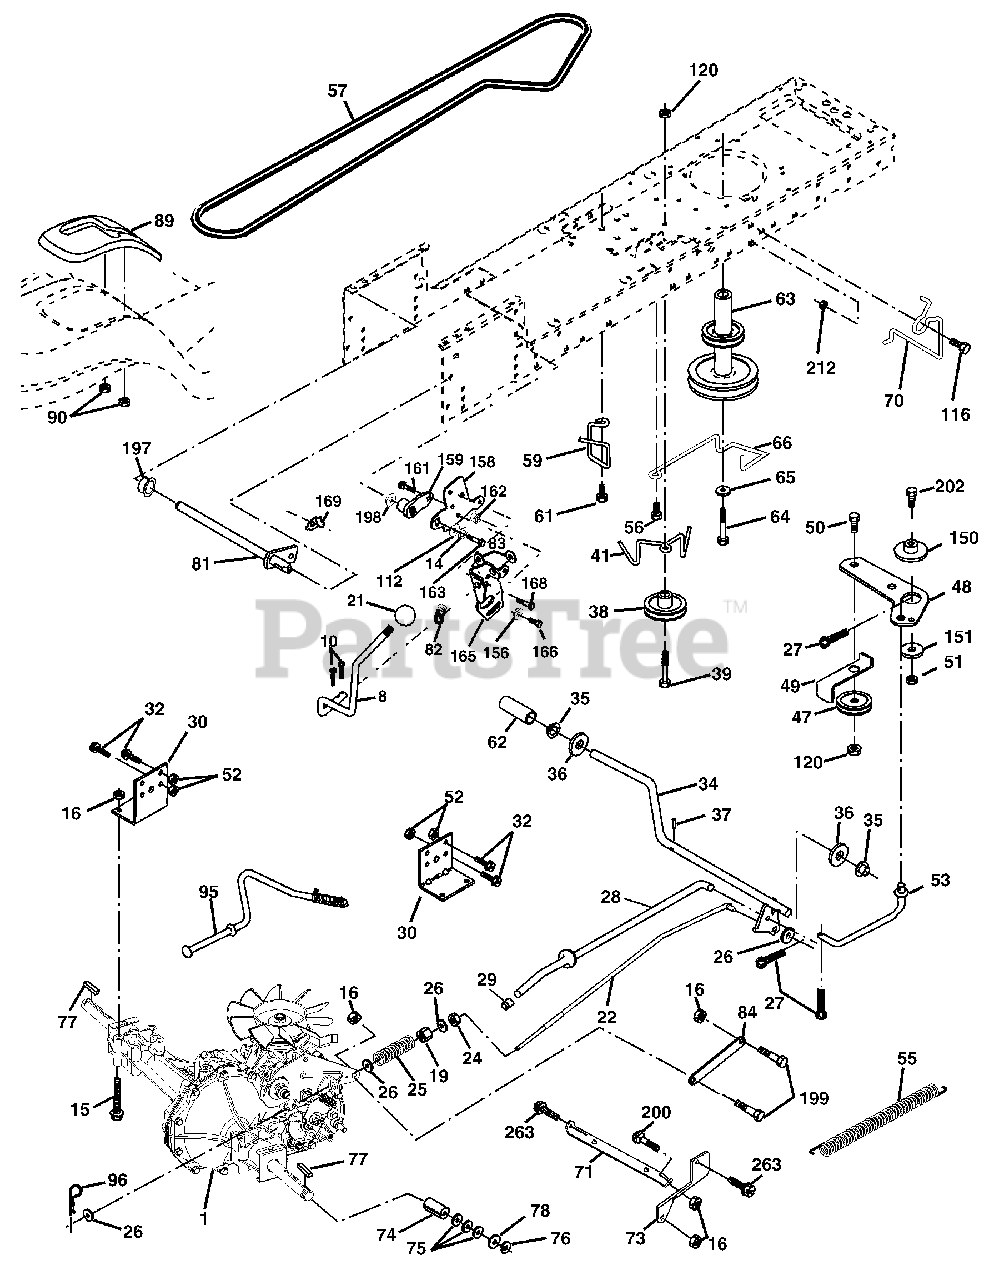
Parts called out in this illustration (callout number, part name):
8	Rod Shift
10	Pin Cotter 1/8 x 1 CAD
14	Washer Lock Hvy Helical
15	Bolt, Hex FLGHD 5/16-18 Gr. 5
16	Nut Lock Hex W/Ins 5/16-18
19	Nut Lock Hex W/Wsh 3/8-16
21	Knob, Round 1/2-13
22	Rod, Brake Hydro
24	Nut
25	Spring, Brake Rod
26	Washer
27	Pin Cotter 1/8 x 3/4 CAD.
28	Rod, Parking Brake
29	Cap, Parking Brake
30	Bracket, Transaxle
32	Bolt Hex Hd 5/16-18 unc x 3/4
34	Shaft, Foot Pedal
35	Bearing, Nylon
36	Washer
37	Pin, Roll
38	Pulley, Composite
39	Bolt Rdhd 3/8-16 unc x 2-3/4 Gr
41	Keeper, Belt Idler
47	Pulley, Idler, V-Groove
48	Bellcrank Clutch Grnd Drv STL
49	Retainer, Belt
50	Bolt Carr Sh 3/8-16 x 1-1/2 Gr. 5
51	Nut Crownlock 3/8-16 unc
52	Nut Crownlock 5/16-18 unc
53	Link, Clutch
55	Spring, Return, Clutch
56	Screw 3/8-16 x 1-1/4
57	V-Belt, Ground Drive
59	Keeper, Center Span
61	Screw 3/8-16 x .875
62	Cover, Pedal
63	Pulley, Engine
64	Bolt Hex 7/16-20 x 4 x Gr. 5-1.5
65	Washer
66	Keeper Belt Engine
70	Guide Belt
71	Strap Torque Lh Hydro
73	Strap Torque Rh Hydro
74	Spacer, Axle
75	Washer 25/32 x 1-1/4 x 16 Ga.
76	E-Ring
77	Key, Square
78	Washer 25/32 x 1-5/8 x 16 Ga.
81	Shaft Asm. Cross Hydro
82	Spring Torsion T/A
83	Washer 17/32 x 3/4 x 16 Ga.
84	Link Transaxle
89	Console, Shift
90	Nut Self-Thd Wsh-HD 1/4 Zinc
95	Control Asm Bypass Hydro
96	Retainer Spring 1" Zinc/Cad
112	Washer 9/32 x 3/4 x 10 Ga.
116	Bolt RDHD SQNK 3/8-16 unc x 1
120	Nut Lock Flg 3/8-16 unc
150	Spacer Retainer
151	Washer 13/32 x 2 x 10 Ga.
156	Washer Srrted 5/16 ID x 1.125
158	Bracket Shift Mount
159	Hub Shift
161	Bolt Rdhd Sqnk 1/4-20 x 3/4 Gr. 5
162	Nut Crownlock 1/4-20 unc
163	Bolt Hex Fin 1/4-20 unc x 1 Gr. 5
165	Bracket Pivot Lever
166	Screw 5/16-18 x 5/8
168	Bolt Shoulder 5/16-18 x .561
169	Plate Fastening Lt
197	Nyliner Snap-In 5/8" ID
198	Washer Nyl 7/8 ID x .105
199	Bolt Shoulder 5/16-18 unc
200	Bolt Rdhd Sqnk 5/16-18 unc x 1
202	Bolt Carr Sh 3/8-16 x 1-3/4 Gr. 5
212	Nut Hex flange Lock
263	Screw Hexwsh Thdr 3/8-16 x 3/4
